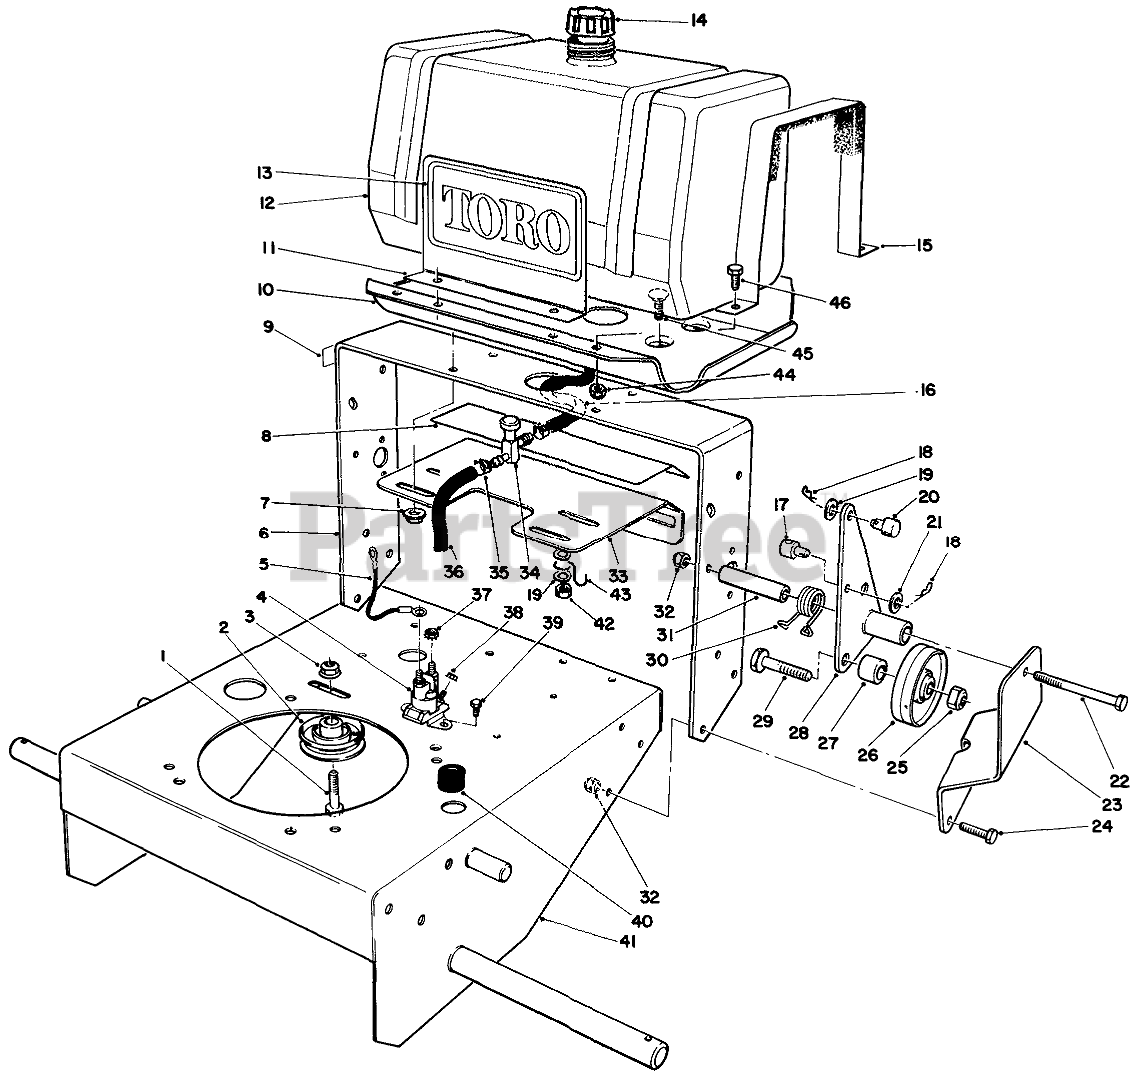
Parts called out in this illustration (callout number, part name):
1	SCREW-HH
2	PULLEY-IDLER
3	NUT-HF
4	Solenoid
5	WIRE-SOLENOID/STARTER
6	Frame-Rear
7	NUT-HF
8	Decal-Ground Speed
9	Decal-Fuel Shut Off
10	PLATE-FUEL TANK
11	DECAL-PLATE
12	TANK-FUEL
13	DECAL
14	GAS CAP ASM
15	STRAP ASM
16	HOSE-FUEL
17	ROD FITTING
18	PIN-COTTER
19	WASHER-PLAIN
20	ROD FITTING
21	WASHER-PLAIN
22	SCREW-HH
23	Support-Idler L.H.
24	SCREW-HH
25	NUT-LOCK, NI
26	IdlerWheel
27	WHEEL IDLER SPACER
28	LH IDLER BRKT WA
29	SCREW-LEVELER
30	SPRING-TORSION, LH
31	PIVOT-IDLER SPACER
32	NUT-LOCK, NI
33	Plate
34	FUEL VALVE
35	CLAMP-HOSE
36	GAS HOSE
37	NUT-KEPS
38	NUT-KEPS
39	SCREW
40	GROMMET
41	Frame
42	NUT-LOCK, NI
43	GAS LINE CLIP
44	NUT-LOCK, NI
45	SCREW-CARR
46	SCREW-HH
